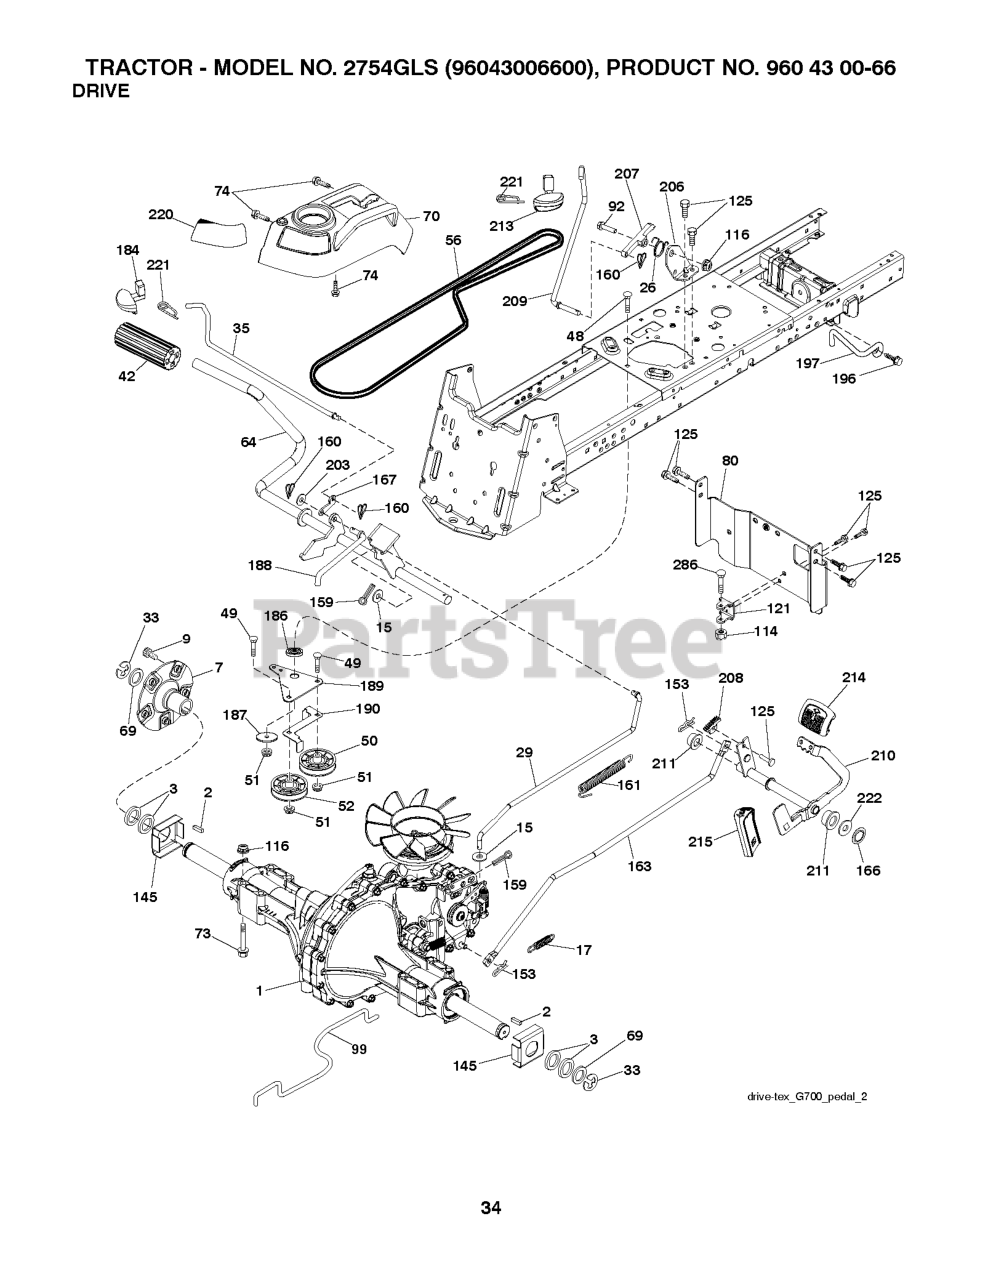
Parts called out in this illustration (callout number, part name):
2	KEY 1/4 X 2.5
7	HUB.ASM.WHEEL.REAR.23"TEX
15	WASHER
17	SPRING.BRAKE.HG3000/3500
26	SPRING.RETURN.CRUISE
33	E RING HYT
35	ROD.BRAKE.PARKING.GT.H
42	PEDAL COVER T
48	BOLT.3/8-16X1.50
50	IDLER.FLAT.910.OFFSET
51	NUT LOCK FLG 3/8-16 UNC
52	IDLER.V-GROOVE.910.OFFSET
64	SHAFT.ASM.PEDAL.BRK.CNTR
70	RP CONSOLE.ASM.PCH.W/TB
73	BOLT HEX FLGHD 5/16-18X3 GR. 5
74	SCREW.HI-LO.CONSOLE
92	BOLT
114	NUT.71038.31-18.HEX.NYLOCK
116	NUT LOCK HEX FLANGE 5/16-18
121	BRACKET STRAP TORQUE
125	SCREW
145	WASHER.AXLE.FLANGE.HG-3000
153	RETAINER M
159	COTTER PIN
160	RETAINER CLIP
161	SPRING, RETURN LT
166	NUT.PUSH.625.2006
167	LATCH.BRAKE.SPRING
184	HANDLE.PARKG.BRK.HUSQ X667
186	SPACER.RETAINER
187	WASHER 12/32X2X10GA
188	RP.LINK.CLUTCH.GROUND.DRIVE
190	KEEPER BELLCRANK ROUND DRIVE
196	SCREW 3/8-16X1
197	BRKT.ANIT-ROTATION.CLUTCH
203	WASHER
206	BRKT.MOUNT.LATCH.CRUIS
207	LATCH.CONTROL.CRUISE
208	GEAR.SECTOR.CONTROL.CR
209	ROD.CONTROL.CRUISE.GT.
210	ROCKER.ASM.PEDAL.CONTR
211	BEARING.NYLON
213	KNOB.CONTROL.CRUSIE.HU
214	PEDAL.FORWARD.HUSQVARNA.DEALER
215	PEDAL.REVERSE.TEX.GT.4
220	REFLECTOR.RH.TEX GT
221	RETAINER.SPRING.CLIP.H
222	WASHER 21/32 X 1-1/4 X 10 GA.
286	Bolt, Carriage 5/16-18 x 2 - 3/4
